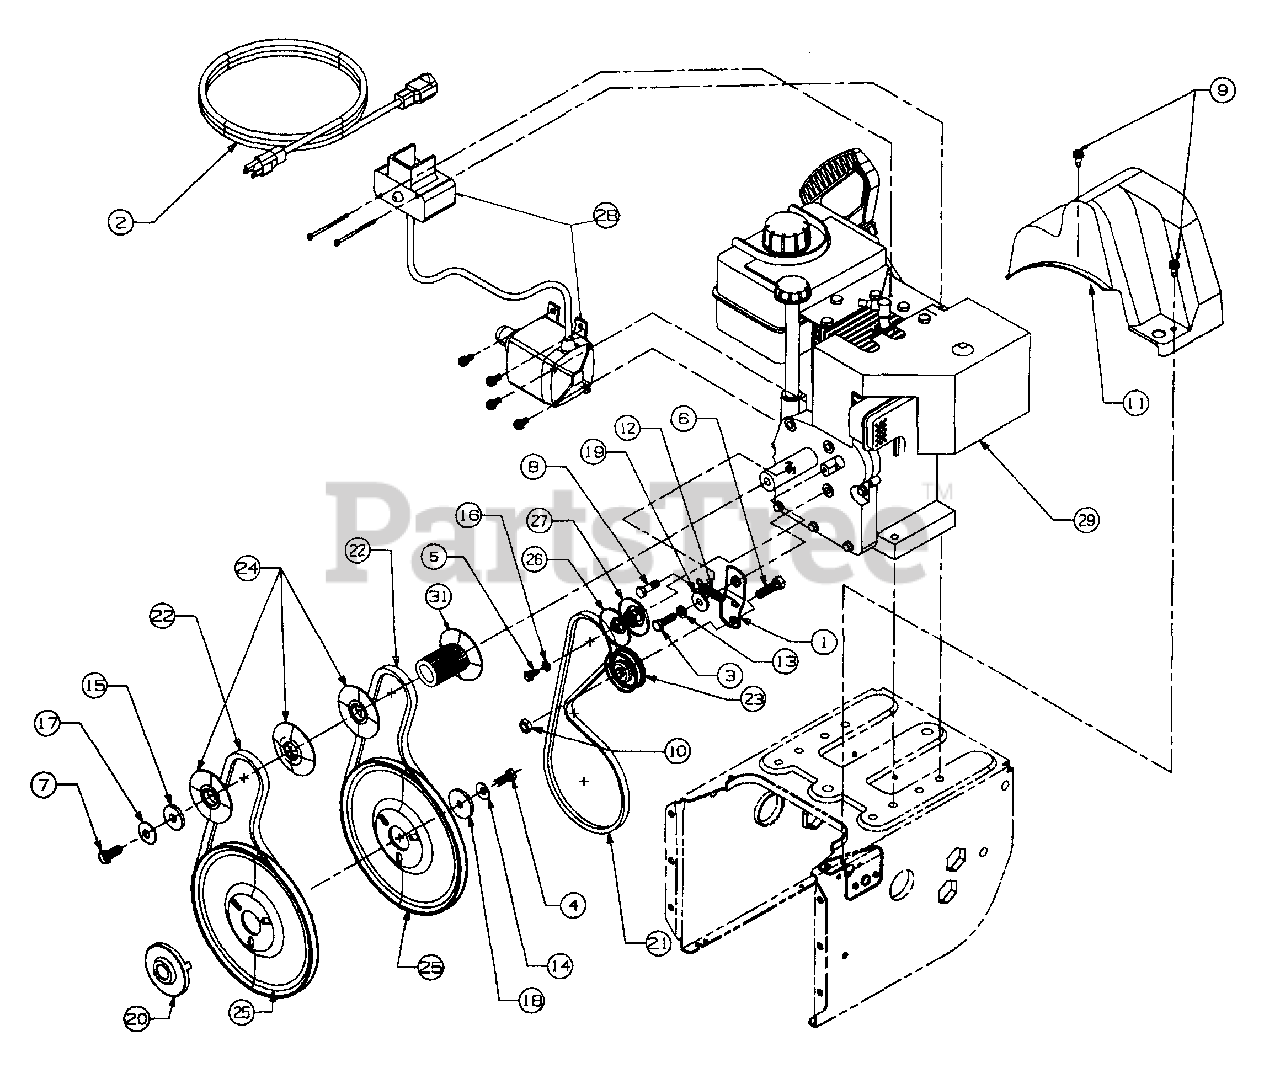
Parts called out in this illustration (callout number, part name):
3	Screw
4	Screw
5	Screw
6	Screw
7	Screw
8	Screw
9	Screw
10	Hex Nut
11	Belt Cover
12	Spring
13	Washer - Lock
14	Washer - Bell
15	Flat Washer
16	Lock Washer
17	Washer
18	Washer
19	Shoulder Spacer
20	Pulley Adapter
21	V-Belt
22	V-Belt
23	Idler, Flat
24	Pulley, Half
25	Pulley Auger
26	Pulley, Half
27	Pulley, Half
28	Starter
29	Engine
31	Pulley, Half
